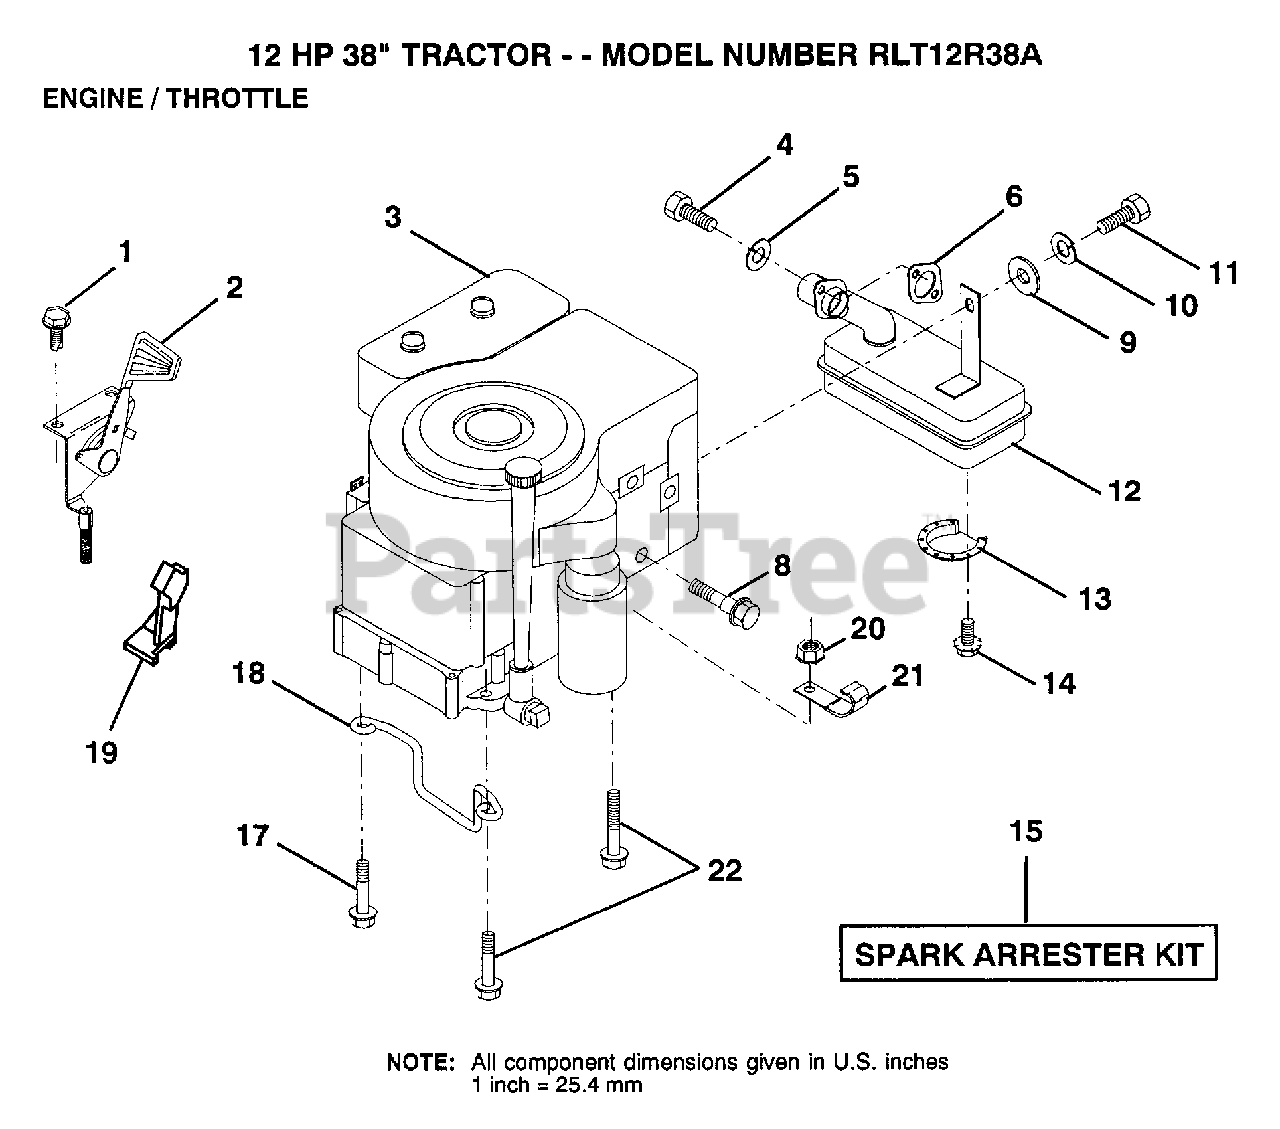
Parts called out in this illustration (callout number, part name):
1	SCREW
2	THROTTLE CONTROL
4	SCREW
5	LOCKWASHER
7	NUT.HEX.5/16-18
8	BOLT T
10	LOCKWASHER
13	DEFLECTOR.222573
17	SCREW LT
18	"KEEPER,DR BELT GR"
20	NUT
21	CLIP T
22	SCREW LT
